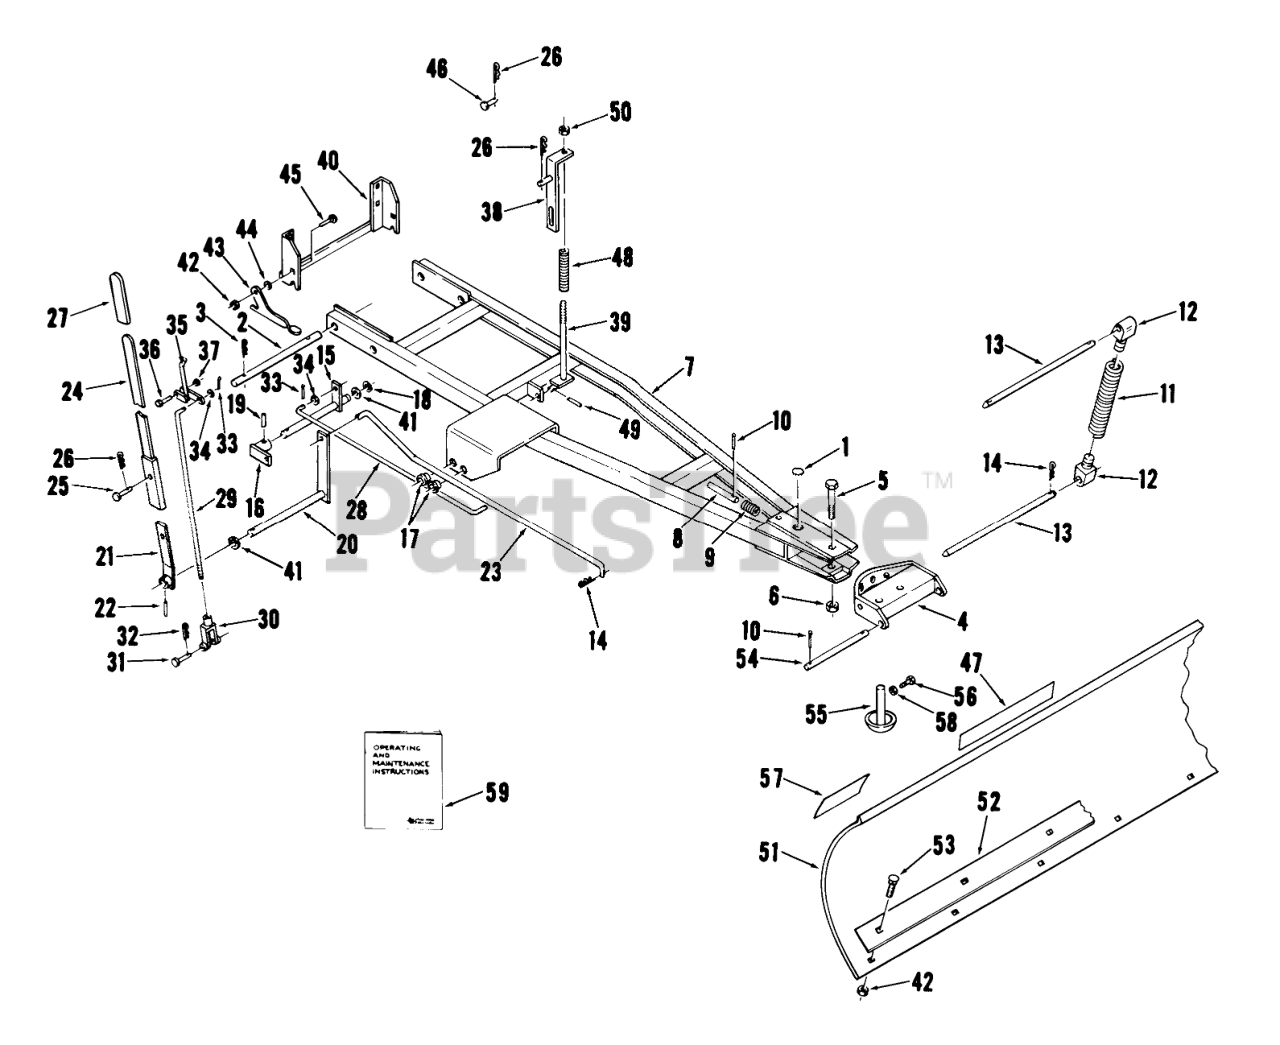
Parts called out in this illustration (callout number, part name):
1	PLUG
2	Mounting Shaft
3	Hairpin
4	Sector and Channel
5	Bolt
6	Nut
7	Frame Assembly
8	Index Pin
9	SPRING-COMPRESSION
11	Spring
12	Lug
13	ROD-TRIP RETURN
14	Hairpin
15	Bushing
16	Sat Collar
17	BUSHING
18	Snap Ring
19	SPIROL PIN 3/8X1 3/4
20	Assembly-Blade Index Arm
21	Assembly-Handle Bar
22	SPIROL PIN 3/8X1 1/2
23	Blade Control Rod
24	HANDLE ASM
25	Pin-Clevis
26	Hairpin Cotter
27	GRIP
28	ROD LOWER INDEX
29	ROD UPPER INDEX
30	YOKE
31	Pin
33	Cotter Pin
35	Assembly Index Lever
36	Bolt
37	Nut
38	Assembly-Lift Bar
39	Assembly Lift Rod
40	Bracket
41	Shim Washer
42	NUT
43	PLATE-LATCHING
44	Washer
45	BOLT
46	Pin
47	DECAL-WHEEL HORSE
48	SPRING
49	Spirol Pin
50	Nut
51	Blade Assembly
52	PLATE-BLADE EDGE
53	Bolt-Carriage
54	ROD-LOWER
55	SKID SHOE ASSY R
56	Screw-Set
57	Caution Decal
58	Nut
59	Operating and Maintenance Instructions
